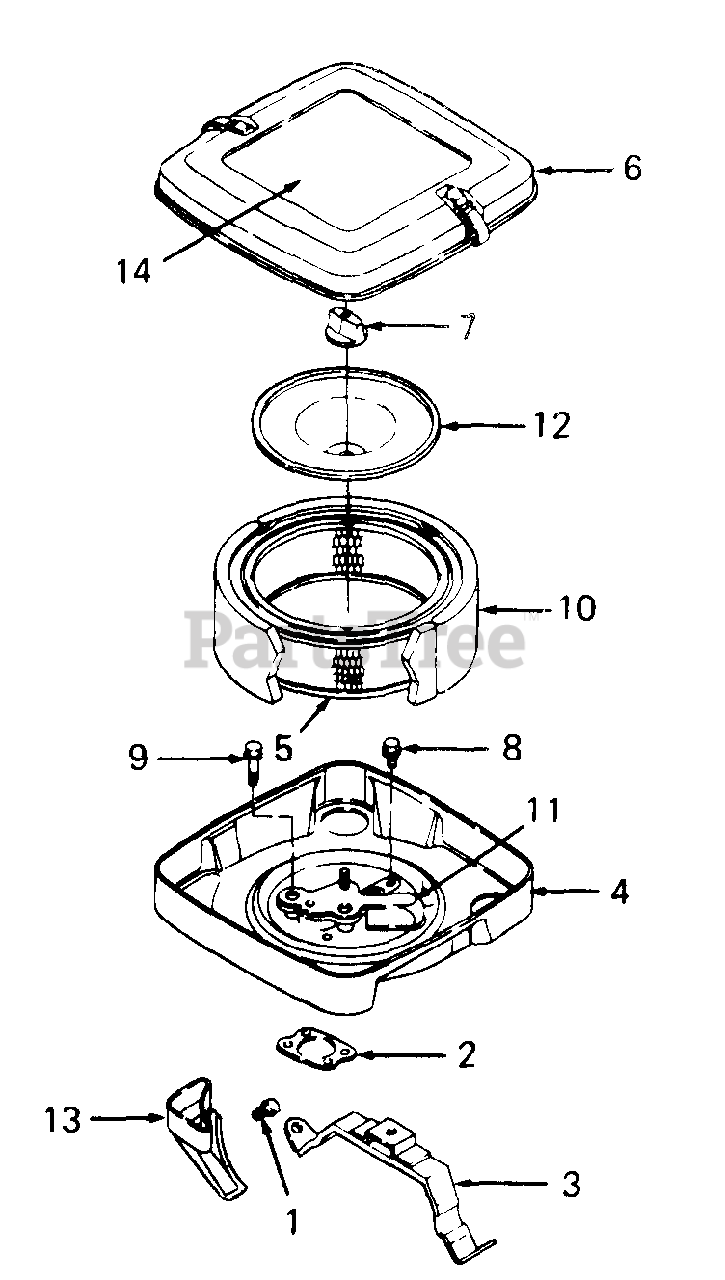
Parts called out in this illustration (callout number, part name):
1	Screw, Sems
2	Gasket, Air Cleaner
3	Bracket, Air Cleaner
4	Base, Air Cleaner
5	Cartridge, Air Cleaner
6	Cover, Air Cleaner
7	Knob, Air Cleaner
8	Screw, Sems
9	Screw, Sems
10	Element, Foam
11	Shield Assy
12	Plate, Air Cleaner
13	Tube, Air Inlet
14	Label, Vanguard Engine
